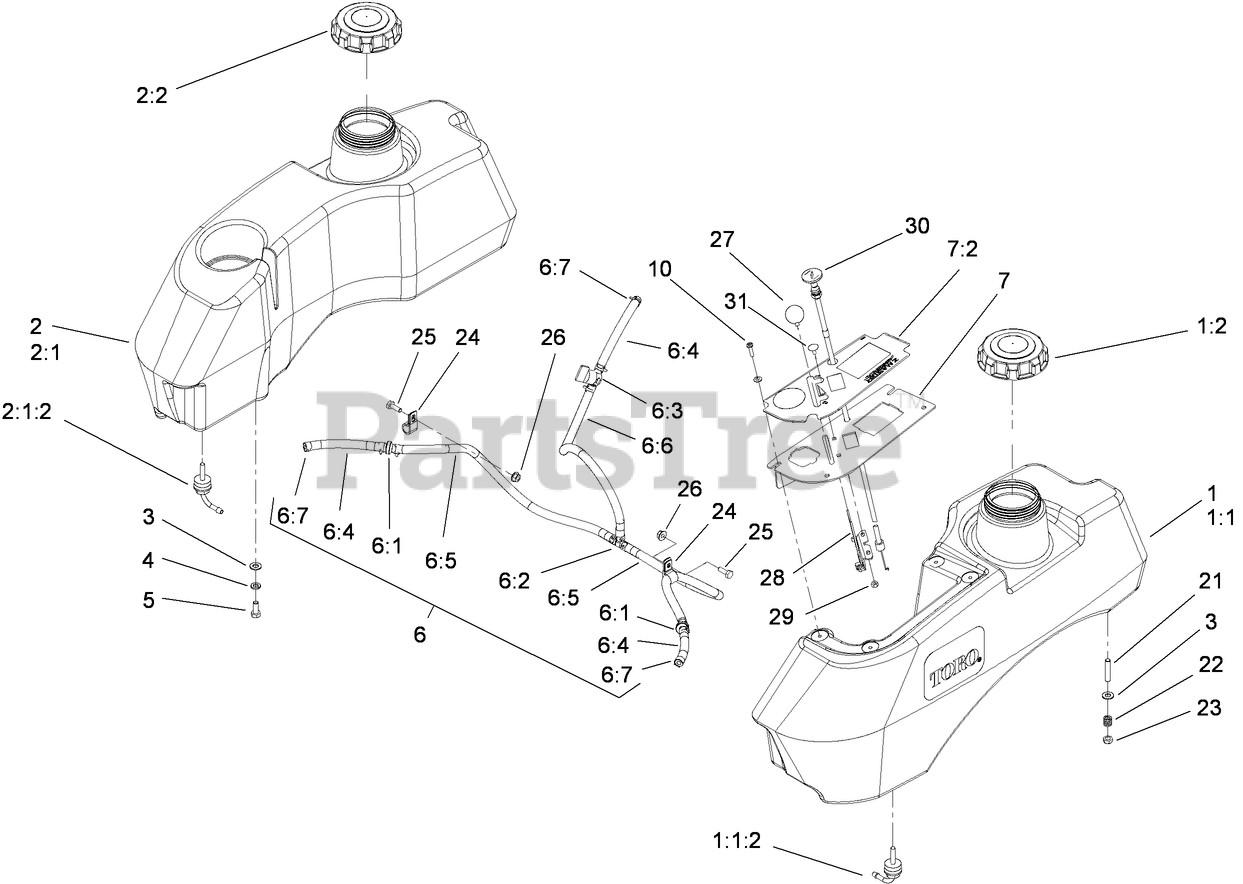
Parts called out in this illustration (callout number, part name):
1	LH FUEL TANK SERVICE KIT
1:1	LH FUEL TANK ASM
1:1:2	FITTING-FUEL, BULKHEAD
1:2	CAP-FUEL, GAS
2	RH FUEL TANK SERVICE KIT
2:1	RH FUEL TANK ASM
2:1:2	FITTING-FUEL, BULKHEAD
2:2	CAP-FUEL, GAS
3	WASHER-PLAIN
4	WASHER-LOCK
5	SCREW-HH
6	Hose-Fuel
6:1	VALVE-CHECK, FUEL
6:2	FITTING-TEE, BARBED
6:3	VALVE-FUEL
6:4	HOSE-FUEL
6:5	HOSE-FUEL
6:6	HOSE-FUEL
6:7	Clamp-Hose
7	CONTROL PANEL ASM
7:2	DECAL-PANEL, CONTROL
10	SCREW-PPH
22	SPRING-TANK, FUEL
23	NUT-LOCK, NI
24	CLIP-LOOM
25	SCREW-HH
26	NUT-HF
27	KNOB-BALL
28	THROTTLE CABLE ASM
29	NUT-LOCK, NI
30	CONTROL-CHOKE, PUSH / PULL
31	BOLT-CARR
